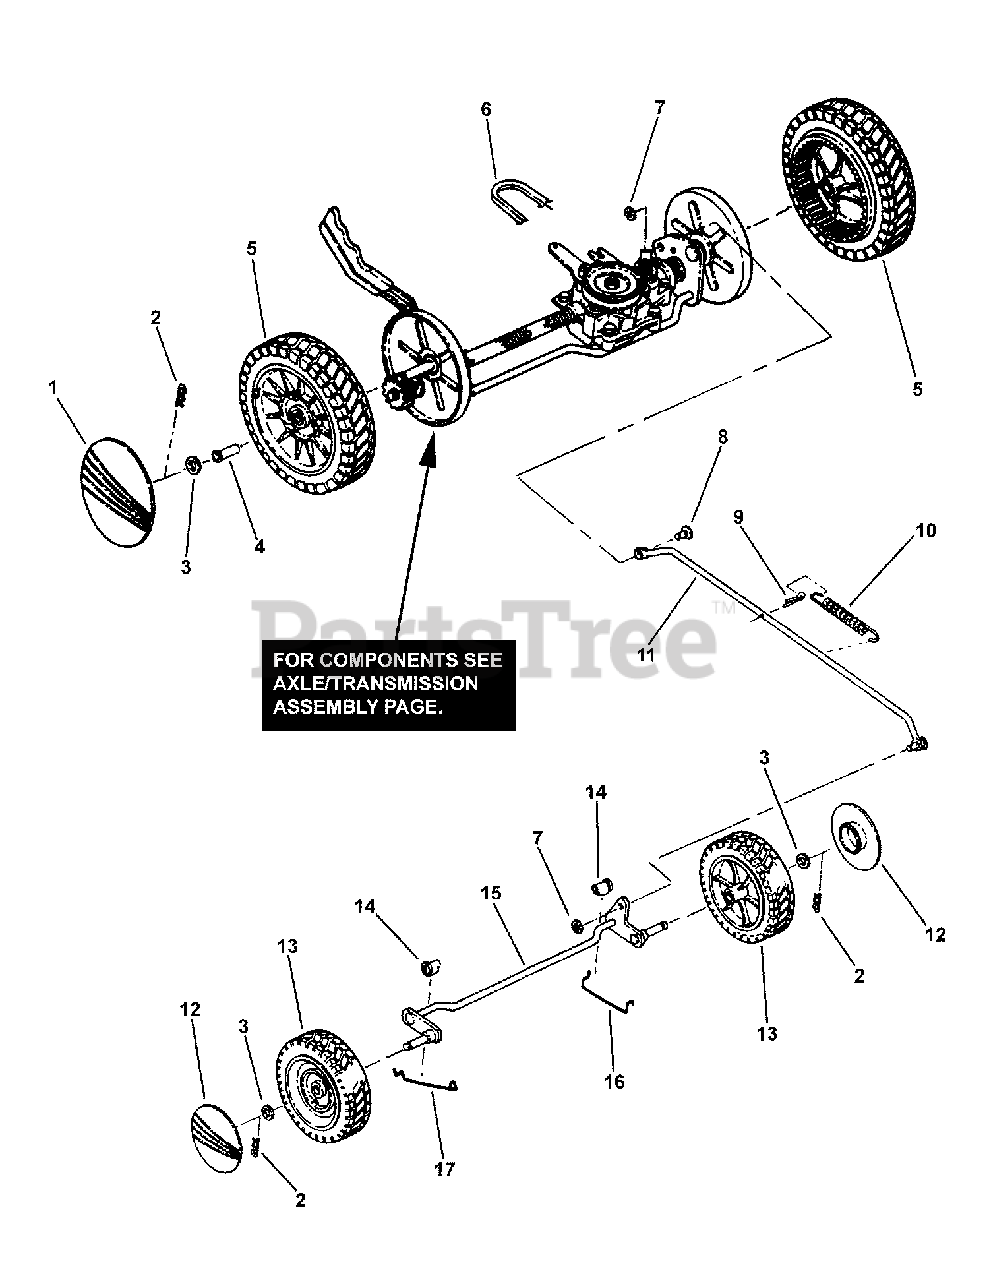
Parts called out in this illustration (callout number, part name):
1	HUB-CAP, Rear Wheel
2	HAIRPIN, 1/16 x 29/32" Cotter
3	WASHER, 1/2" Flat
4	BUSHING, Rear Wheel
5	ASSEMBLY, Rear Drive Wheel - 9.0 x 2.0
6	BELT, Traction (3L Sect, 33.200" effective length)
7	RETAINER, Wheel
8	PIN, 3/8 x 5/8" Tie Bar
9	PIN, 1/8 x 3/4" Cotter
10	SPRING, Tie Bar
11	WELDMENT, Tie Bar
12	HUB-CAP, Front Wheel
13	ASSEMBLY, Wheel Front
14	BUSHING, Front Axle
15	WELDMENT, Front Axle
16	SPRING, Axle Retaining Left Hand
17	SPRING, Axle Retaining Right Hand
